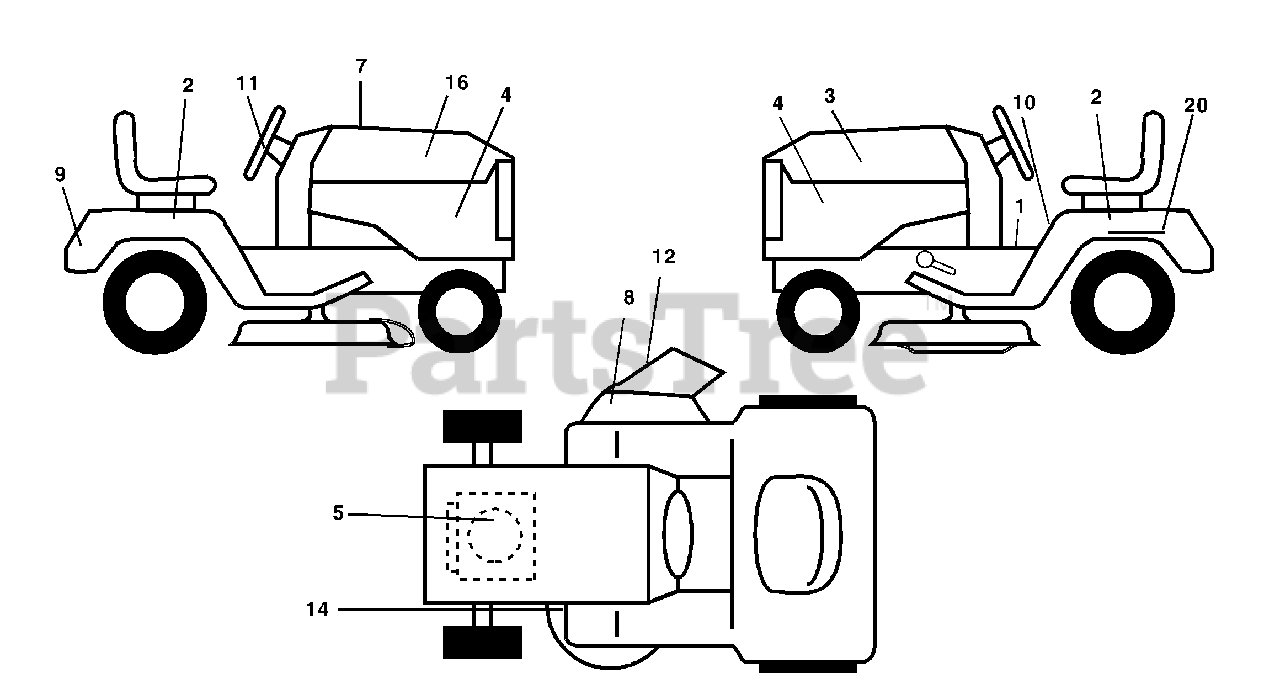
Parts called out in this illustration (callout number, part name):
1	Decal Oper
2	Decal Fender Auto
3	Decal Hood LH
4	Decal Side Panel Logo
5	Decal HP Engine
7	Decal Replacement Parts
8	Decal Deck "B" 42"
9	Decal Fender Logo
10	Decal Fender Danger E/F
11	Decal Ins Strg Whl
12	Decal Mower Warn Keep Hand Away
14	Decal V-Belt Schematic
16	Decal Hood Rh
20	Decal Bat Dan/Psn
